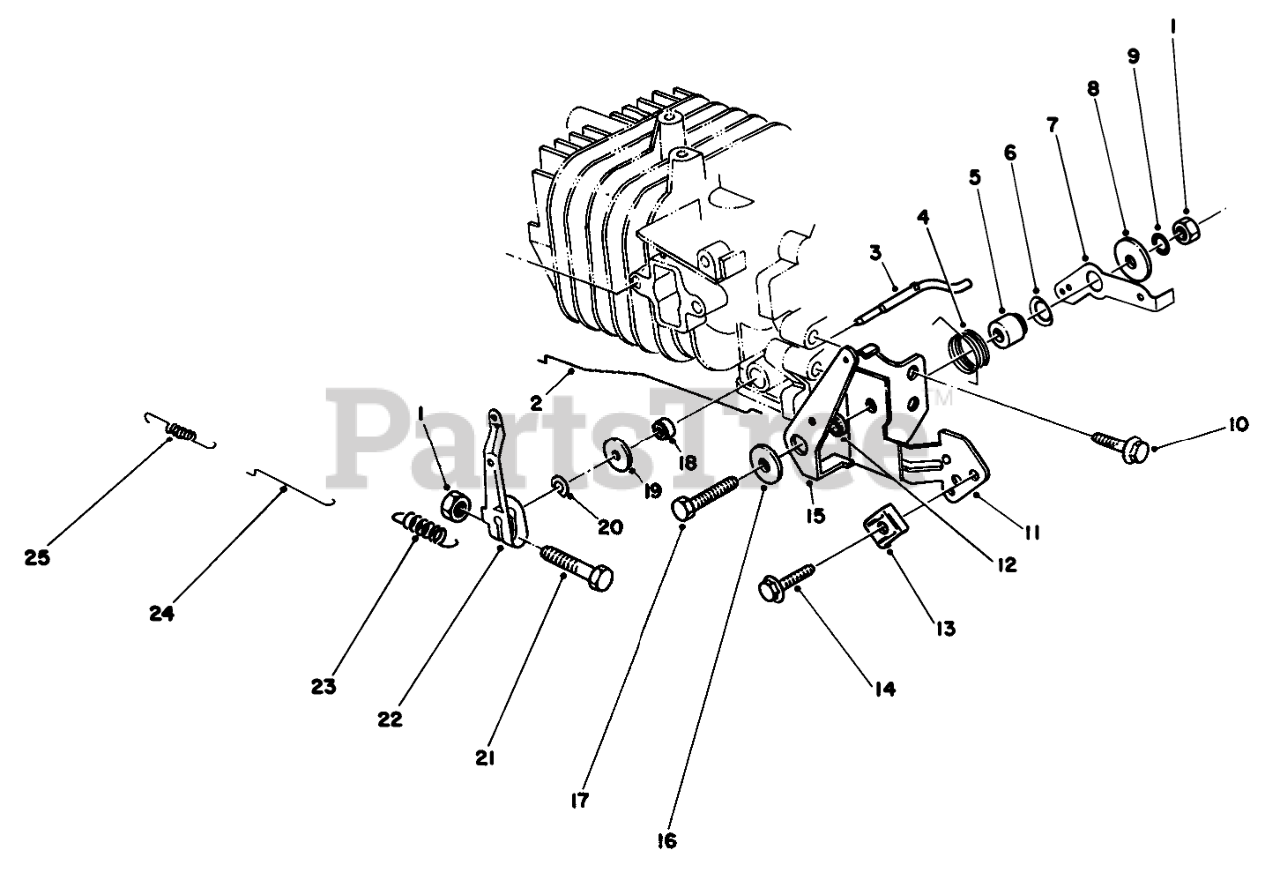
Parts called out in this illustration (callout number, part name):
2	CHOKE ROD
3	Shaft-Govemor
4	SPRING-CHOKE LEVER
5	Gov Lever Spacer
6	Washer-Gov. Spring Lever
7	LEVER-SPRING, GOVERNOR
8	WASHER
9	LOCKWASHER
11	BRACKET-THROTTLE, CONTROL
12	SPACER-CHOKE LEVER
13	CLAMP
15	LEVER-CONTROL, CHOKE
16	WASHER
18	SEAL-OIL
19	WASHER
20	E-RING
22	GOVERNOR ARM
23	SPRING-GOVERNOR
24	ROD-CARBURETOR
25	SPRING
